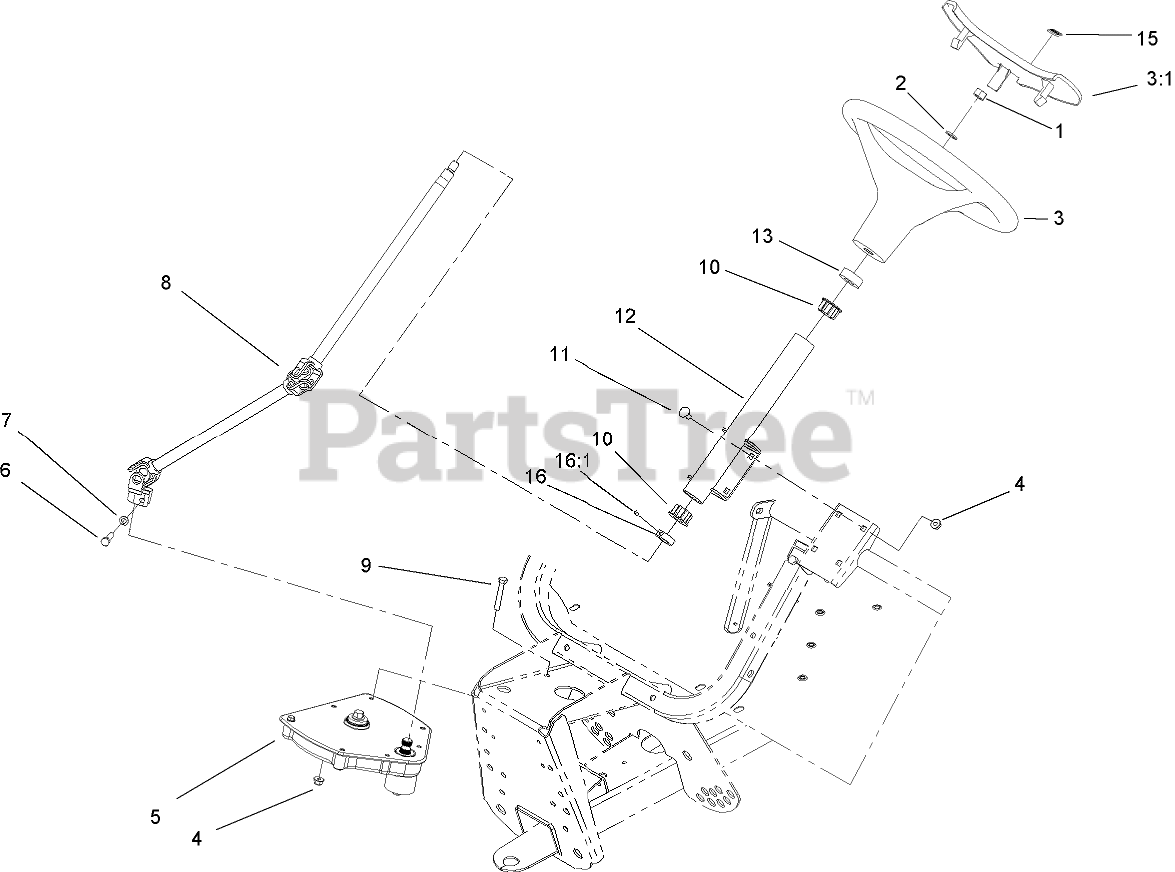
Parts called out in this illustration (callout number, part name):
1	NUT-HEX
2	WASHER-FLAT
3	WHEEL-STEERING
3:1	COVER-WHEEL, STEERING
4	NUT-HF, NI
5	STEERING GEARBOX ASM
6	SCREW-CAP, HH
7	WASHER-LOCK
8	SHAFT-STEERING
9	SCREW-HH
10	BUSHING-STEERING, UPPER
11	BOLT-CARR
12	COLUMN-STEERING
13	COVER-DUST
15	DECAL
16	COLLAR
16:1	SCREW-HSH
